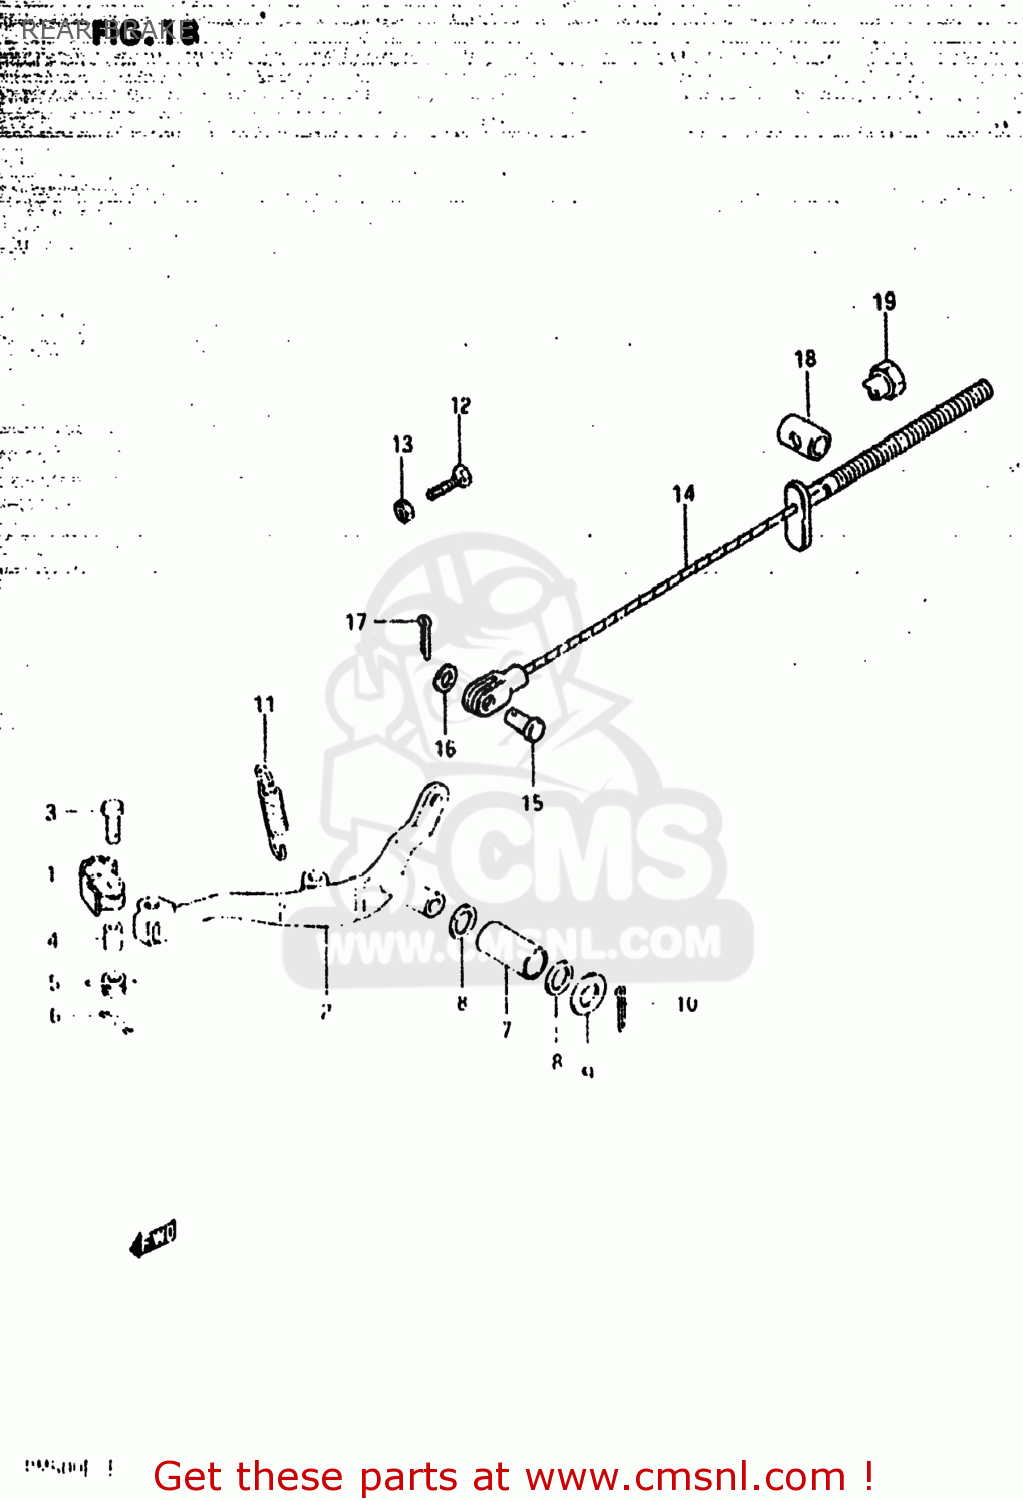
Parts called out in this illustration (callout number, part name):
1	PEDAL,BRAKE
2	ARM,BRAKE PEDAL
3	PIN
4	SPACER(6.5X10.5X6.5)
5	SPRING
6	PIN
7	BUSHING
8	O RING(D:2.2,ID:11.8)
9	WASHER
10	PIN 30X20
11	SPRING
12	SCREW(6X23)
13	NUT
14	CABLE,RR BRAKE
15	PIN(L:17.5)
16	WASHER
17	PIN 20X20
18	PIN
19	NUT (6MM)
